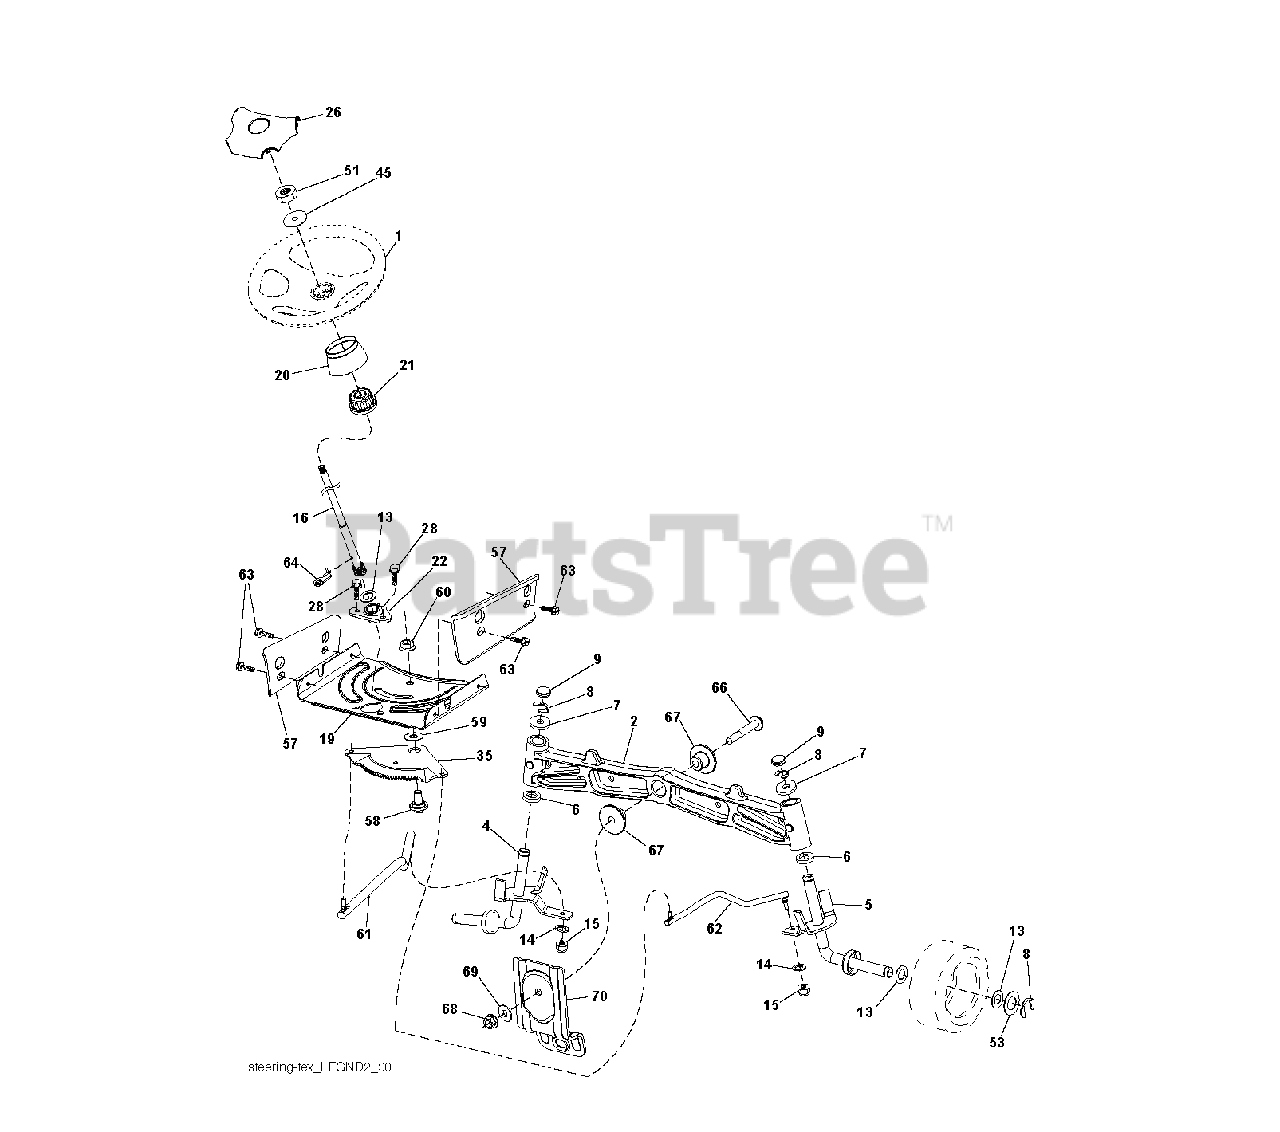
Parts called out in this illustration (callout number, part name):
1	WHEEL.STEERING.STDSRR.BLK/OV
2	AXLE.CAST.IRON
4	SPINDLE.WELDED.LH.15"TEX
5	SPINDLE.WELDED.RH.15"T
8	RING CLIP
9	CAP.SPINDLE
14	WASHER, LOCK 3/8
15	NUT CROWNLOCK 3/8-24
16	SHAFT.STEER.STEALTH.DD
19	PLATE.STEER.DDL.NLT/NG
21	ADAPTER, WHEEL STNG..
22	STEERING.SUPT.LOWER.
26	CAP.WHL.STRNG.STDSRRD.SRS.BLK
28	SCREW, 3/8-16X3/4
35	GEAR.SECTOR.PLATE.DDL.
45	WASHER 9/16"ID, 2 3/8"OD
51	NUT.HEX.1/2-20
53	WASHER.HARDENED
57	BRACKET.UPSTOP.TEX
58	BOLT.SHOULDER.SECTOR.P
59	WASHER.THURST.SECTOR.S
60	NUT FLANGE LOCK 5/8-11
61	DRAGLINK.LH.BALLSTUD.D
62	DRAGLINK.RH.BALLSTUD.D
63	SCREW
64	RETAINER.CLIP.SPRING.S
66	BOLT HEX FGHD 7/16-14 X 3 SERR
67	BUSHING.PM.FRONT AXLE
68	NUT.LOCK.FLANGE.7/16
69	WASHER.1.5X.505X.118
70	BRKT.DECK.SUSPENSION.F
